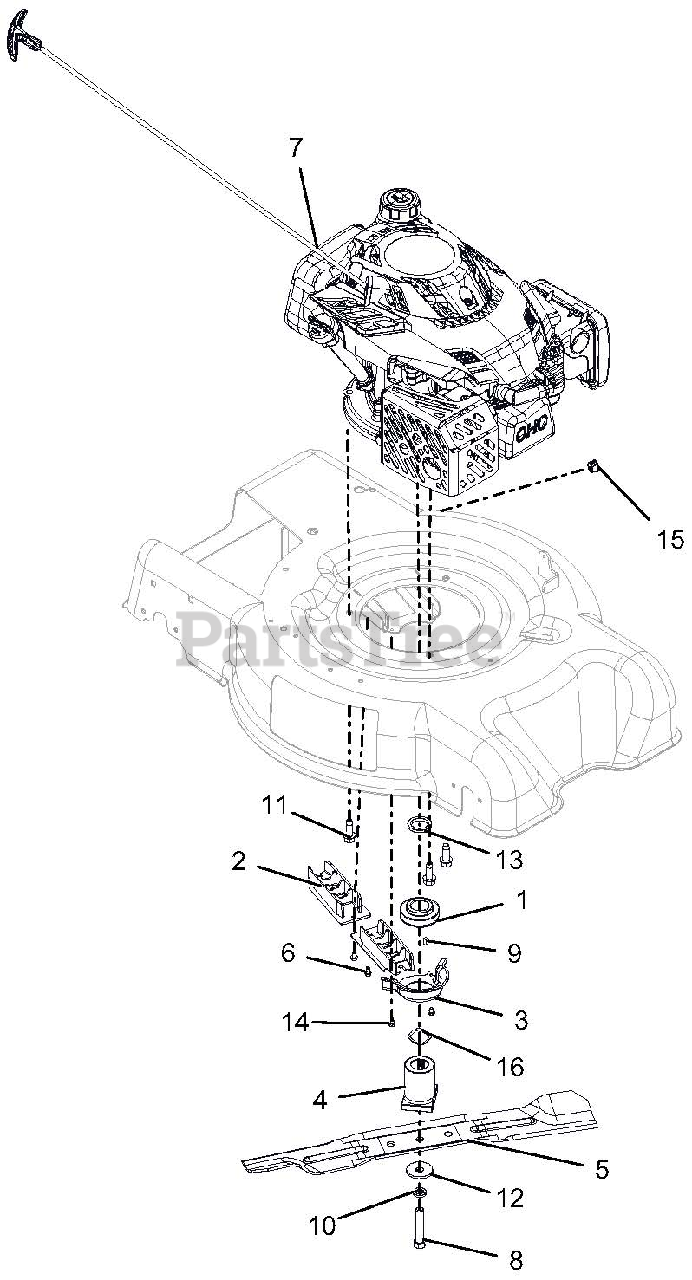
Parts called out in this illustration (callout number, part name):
1	PULLEY, GROUND DRIVE, LM
2	GUIDE, BELT INNER
3	GUIDE, BELT CRANK
4	ADAPTER, BLADE
5	BLADE, MOWER 21" HIGH LIFT
6	SCR-TAP 10-24X.375 PRE-COAT 80
7	ENGINE, SUBARU 175CC VERT. ES
8	@BLT-HEX .4375-20X2.25 GR8 YWZ
9	KEY-SQ .188X.188X.375
10	@WSHR-LK .44X.109 REG YWZC
11	@SCR-TAP .38-16X1.00 HWH TR YZ
12	WSHR-FL-STL .4375X1.50X.125 YZ
13	SPCR, 1.00 X 1.375 X .179
14	SCR-TAP 10-24X.25 CRSLPH TR YZ
15	PLUG, DOME-BLACK, .625 DIA
16	WASHER - WAVE 1.09X1.37X.016
